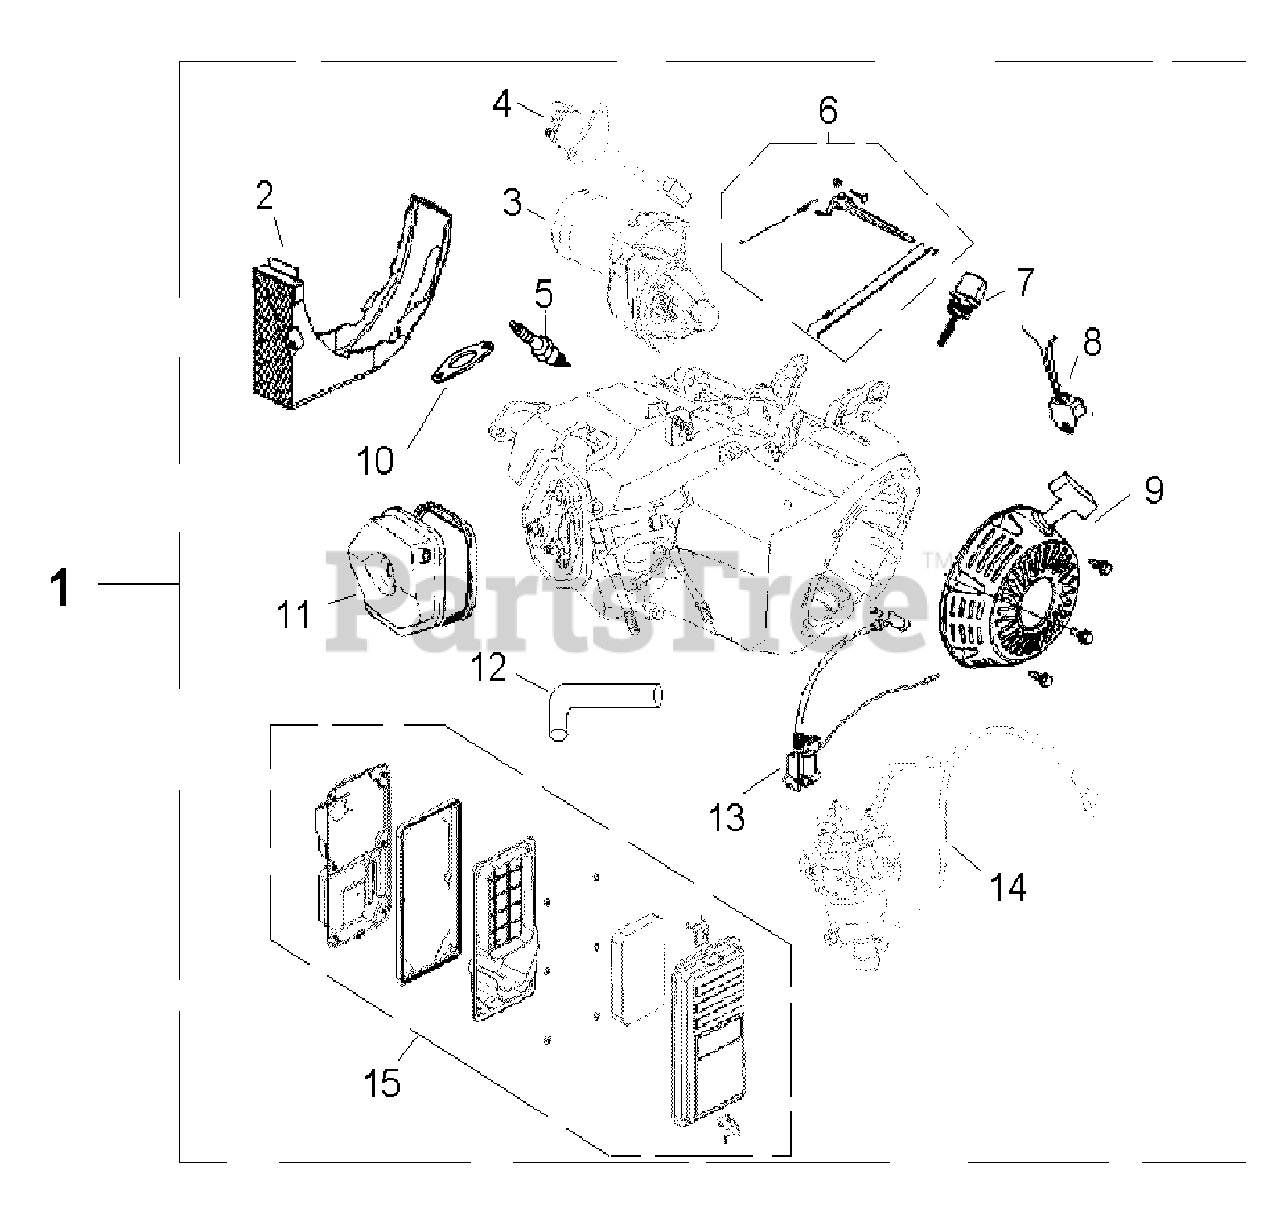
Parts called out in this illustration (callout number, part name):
3	STARTER MOTOR
4	CONTACTOR ASSY.
6	CONTORL ASSY.
7	CAP COMP., OIL FILLER
8	ALART UNIT,OIL
9	STARTER ASSY.
10	GASKET, EX., PIPE
11	COVER COMP. HEAD
13	COIL ASSY., IGNITION
14	CARBURETOR ASSY.
